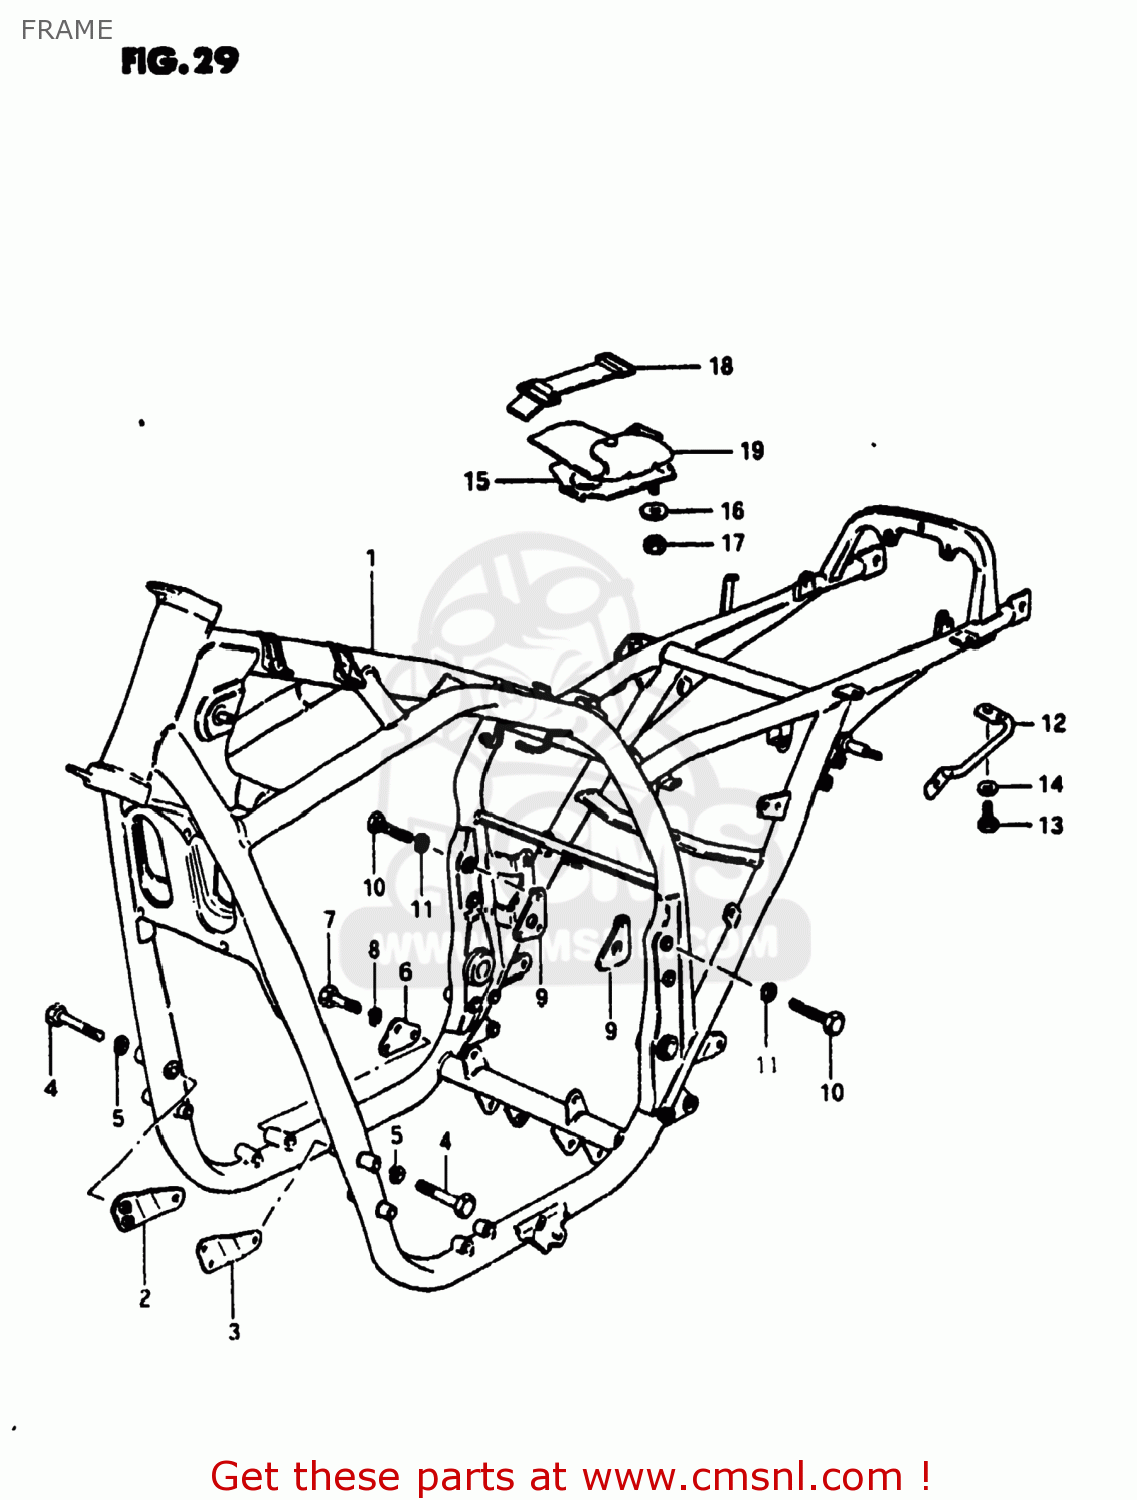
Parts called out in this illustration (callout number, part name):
1	FRAME (BLACK)
2	PLATE, NO.1 RH (BLACK)
3	PLATE, NO.1 LH (BLACK)
4	BOLT
5	LOCK WASHER
6	PLATE,ENGINE MOUNTING
7	BOLT
8	LOCK WASHER
9	PLATE,ENGINE MOUNTING
10	BOLT
11	LOCK WASHER
12	GRIP,FRAME
13	BOLT
14	WASHER
15	HOLDER,TOOL
16	WASHER
17	NUT
18	BAND
19	TOOL SET
